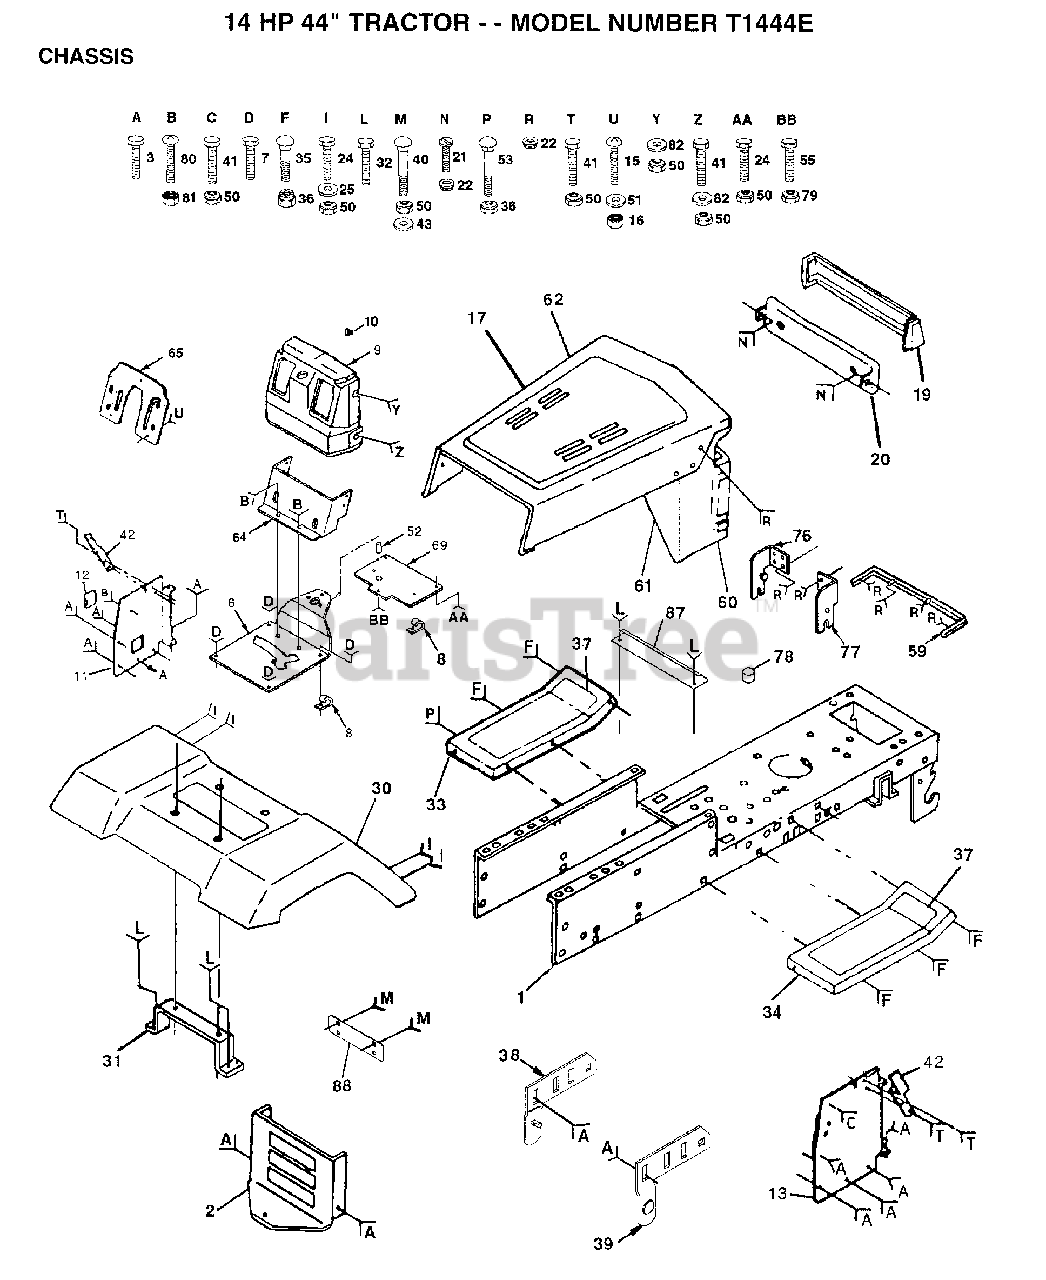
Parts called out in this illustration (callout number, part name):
3	SCREW
7	SCREW
8	CLIP T
10	PLUG-DASH T
11	PANEL.DASH.LH
12	COVER ACCESS
13	PANEL.DASH.RH
15	SCREW
16	NUT
21	SCREW SPECIAL
22	PAL NUT LT
24	BOLT
25	WASHER
31	BRACKET SUPT FEND
32	SCREW
35	BOLT
36	NUT
37	FOOTREST PAD
38	BRACKET ASM LH
39	BRACKET ASM RH
40	BOLT D
41	BOLT
42	BRACKET.ASM.SUPT.
43	WASHER
50	NUT
51	WASHER PM
52	SPACER
55	BOLT
59	"STRAP,GRILL"
60	GRILLE ASM WELD
64	DASH-LOWER YT
65	PLATE DASH SILKSC
69	PLATE.SUPT.BATTER
76	BRACKET.RH
77	BRACKET.LH
79	NUT
80	SCREW
82	WASHER
87	SPACER FENDER LT
88	PLATE EXTEN FEND
